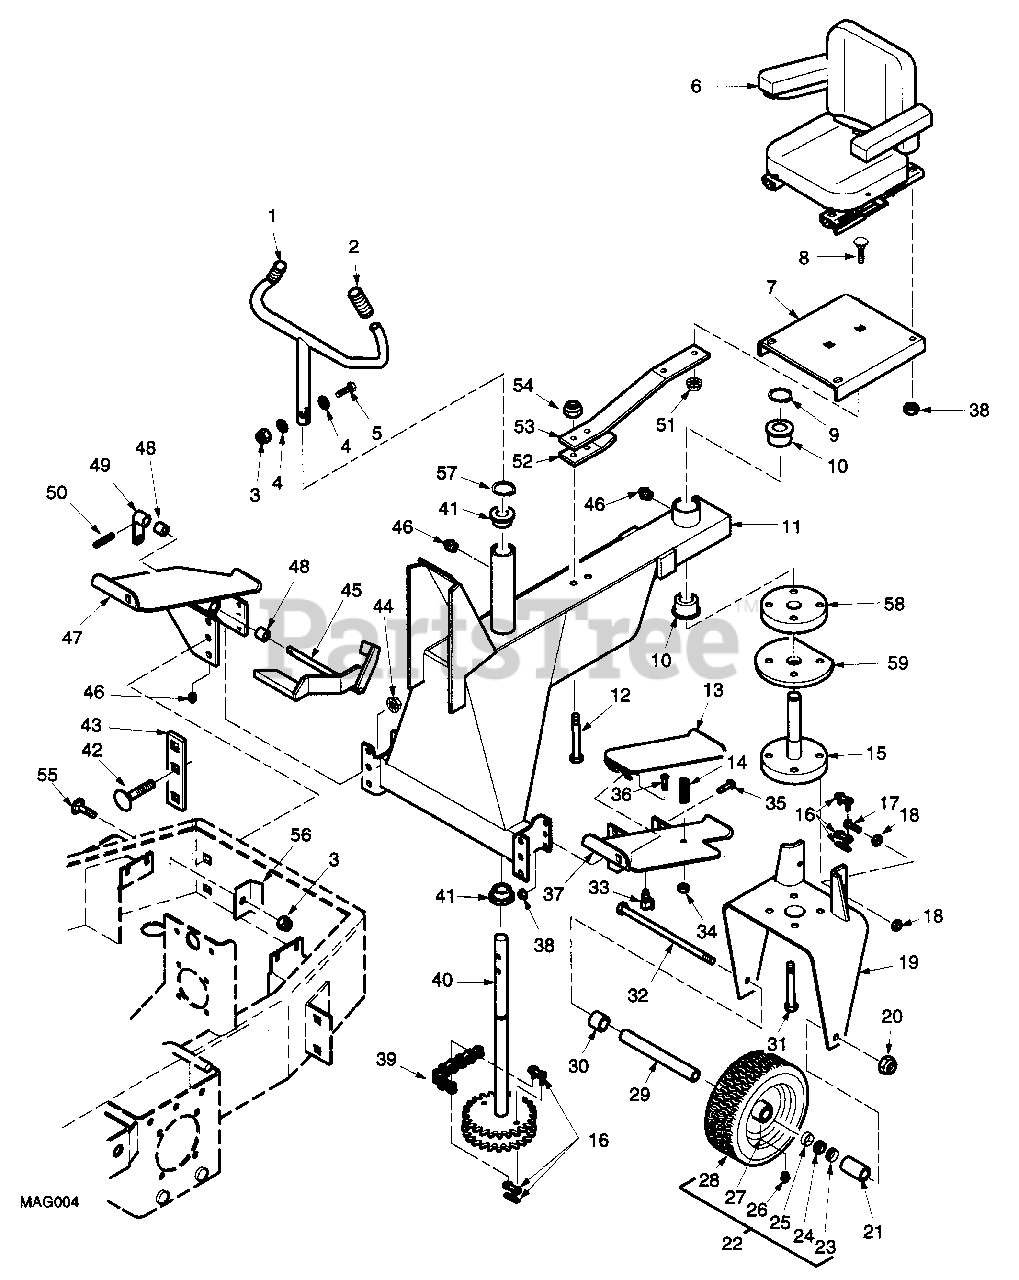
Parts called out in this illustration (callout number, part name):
1	HANDLE, STEERING(INCLUDES 2)
2	HANDLE GRIP
3	HEX LOCKNUT, ELASTIC STOP, 5/16-18
4	FLATWASHER, 5/16(.375 X .875 X .083)
5	BOLT, HEX HEAD, 5/16-18 X 1.75
6	SEAT(WITH ADJUSTER RAILS)
7	PLATE, SEAT MOUNT
8	CARRIAGE BOLT, 3/8-16 X 1-1/4
9	RETAINING RING - 1.125 EXT
10	BUSHING, OILITE - 1-1/8 ID
11	FRAME, STEERING
12	BOLT, HEX HEAD, 7/16-14 X 3-1/2
13	PEDAL, FOOT INTERLOCK
14	SPRING, FOOT INTERLOCK SWITCH
15	PIVOT, REAR YOKE
16	CONNECTOR LINK, #50 CHAIN
17	ANCHOR BOLT, CHAIN
18	NUT, JAM, 3/8-16
19	YOKE, REAR
20	HEX LOCKNUT, ELASTIC STOP, 5/8-11
21	SPACER, REAR WHEEL
22	REAR WHEEL ASSEMBLY(INCLUDES 23-29)
23	SEAL, GREASE
24	BEARING CONE
25	BEARING CUP
26	GREASE FITTING
27	RIM(INCLUDES 23, 24, 25 & 26)
29	SLEEVE, REAR TIRE
30	SPACER, REAR WHEEL
31	BOLT, HEX HEAD, 7/16-14 X 2-1/2
32	BOLT, HEX HEAD, 5/8-11 X 11-1/4
33	SWITCH, FOOT INTERLOCK
34	HEX LOCKNUT, ELASTIC STOP, 1/4-20
35	SERR. FL. HEX HEAD CAPSCREW, 5/16-18 X 1.00
36	SCREW, FLAT HED, #10-32 X 3/4
37	FOOTPLATE, LH
38	SERR. FL. HEX NUT, 5/16-18
39	CHAIN, STEERING - #50
40	SHAFT, STEERING
41	BUSHING, BRONZE - 7/8 ID
42	CARRIAGE BOLT, 1/2-13 X 1-3/4
43	PAD, REINFORCEMENT
44	SERR. FL. HEX NUT, 1/2-13
45	FOOT PEDAL
46	GREASE FITTING
47	FOOTPLATE, RH
48	BUSHING, OILITE - 3/4 ID
49	FOOT PEDAL ARM
50	PIN, DRIVE LOCK, 3/16 X 1-1/4
51	SERR. FL. HEX NUT, 3/8-16
52	REINFORCEMENT, SPRING
53	SPRING, SEAT SUPPORT
54	HEX LOCKNUT, ELASTIC STOP, 7/16-14
55	CARRIAGE BOLT, 5/16-18 X 3/4
56	RETAINER, BOLT
57	RETAINING RING, 7/8 EXT
58	GUIDE, TOP CHAIN
59	DIVIDER, CHAIN SPACER
